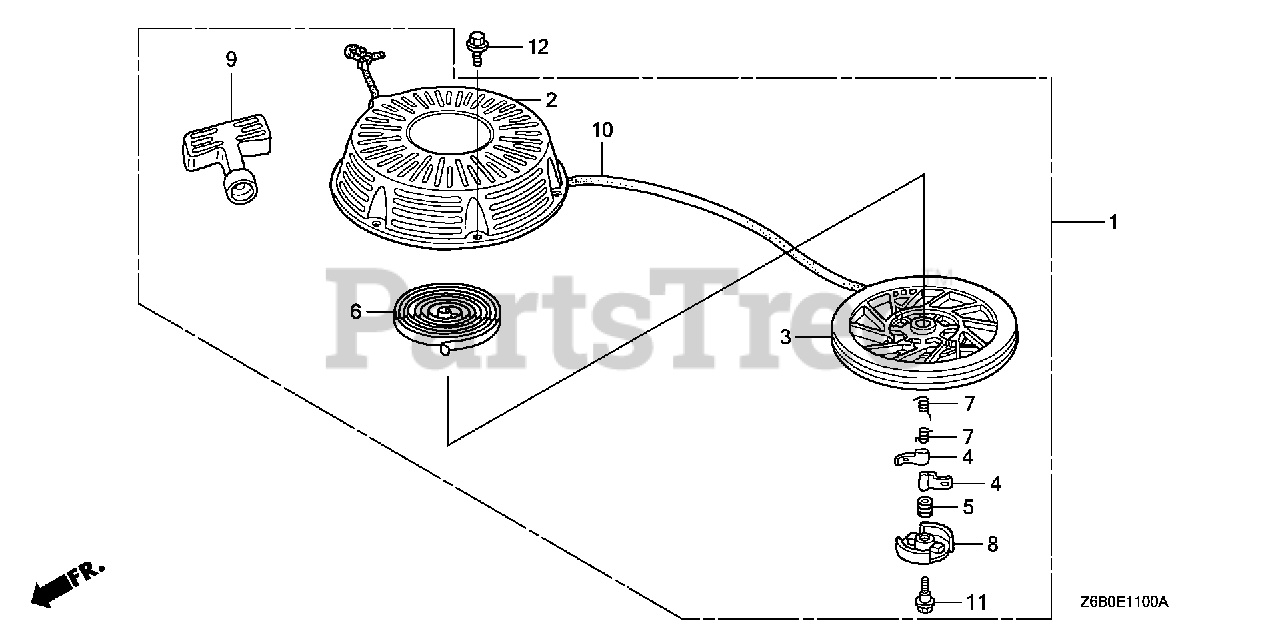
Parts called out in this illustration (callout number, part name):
1	STARTER ASSY., RECOIL *NH105* (MAT BLACK)
1	STARTER ASSY., RECOIL *R280* (POWER RED)
2	CASE, RECOIL STARTER *NH105* (MAT BLACK)
2	CASE, RECOIL STARTER *R280* (POWER RED)
3	PULLEY, RECOIL STARTER
4	RATCHET, STARTER
5	SPRING, FRICTION
6	SPRING, STARTER RETURN
7	SPRING, RATCHET
8	RETAINER, SPRING
9	GRIP, STARTER
10	ROPE, RECOIL STARTER (#6X64") (N/A: USE P/N 08560-ZG921-11)
11	SCREW, CENTER
12	BOLT, FLANGE (6X8)
